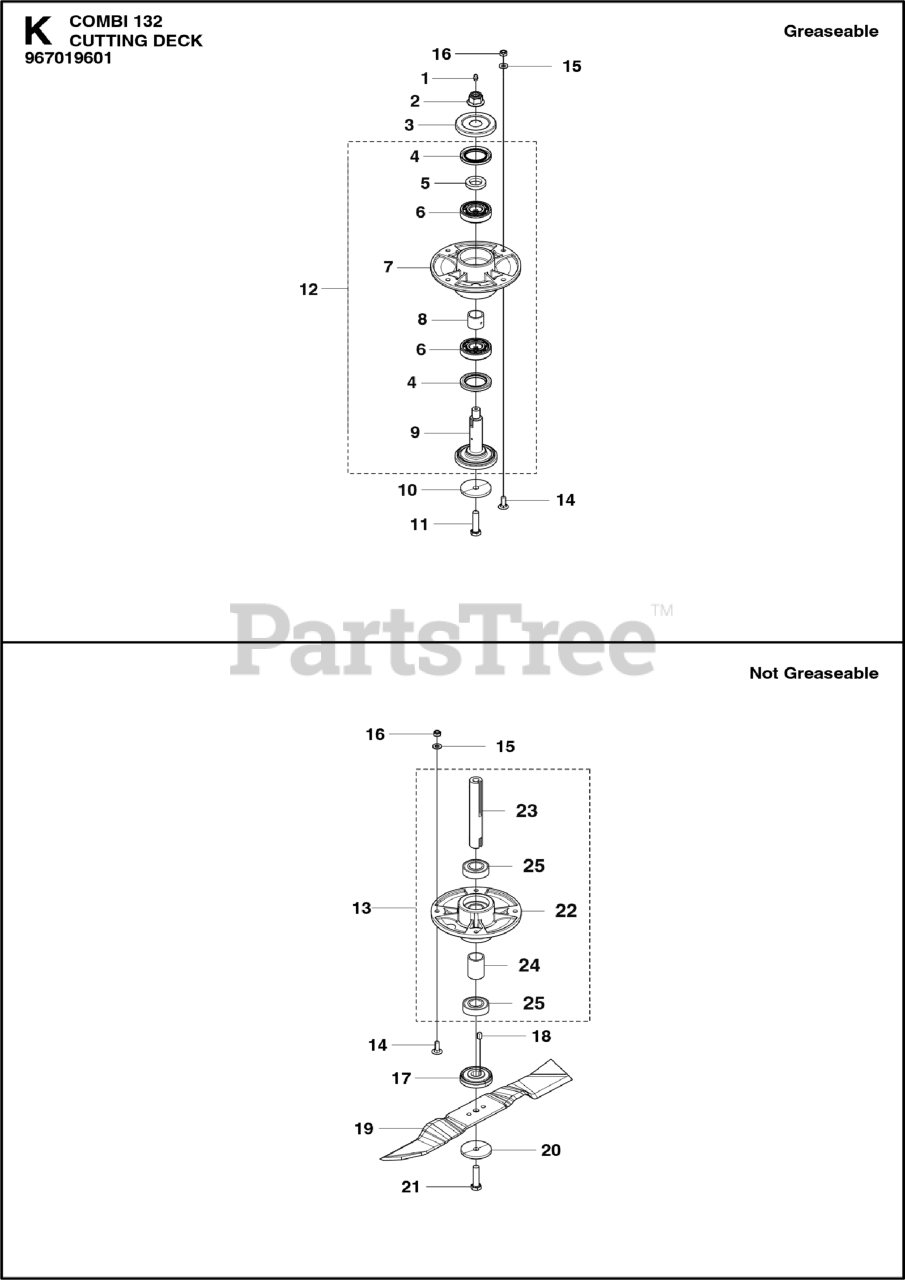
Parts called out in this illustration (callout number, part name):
1	GREASE NIPPLE
6	BALL BEARING 6305 C3
15	WASHER BRB 8.4X17
16	LOCKNUT M8
19	BLADE REAR DISCHARGE/MULCH C13
22	BEARING HOUSING
25	BALL BEARING
